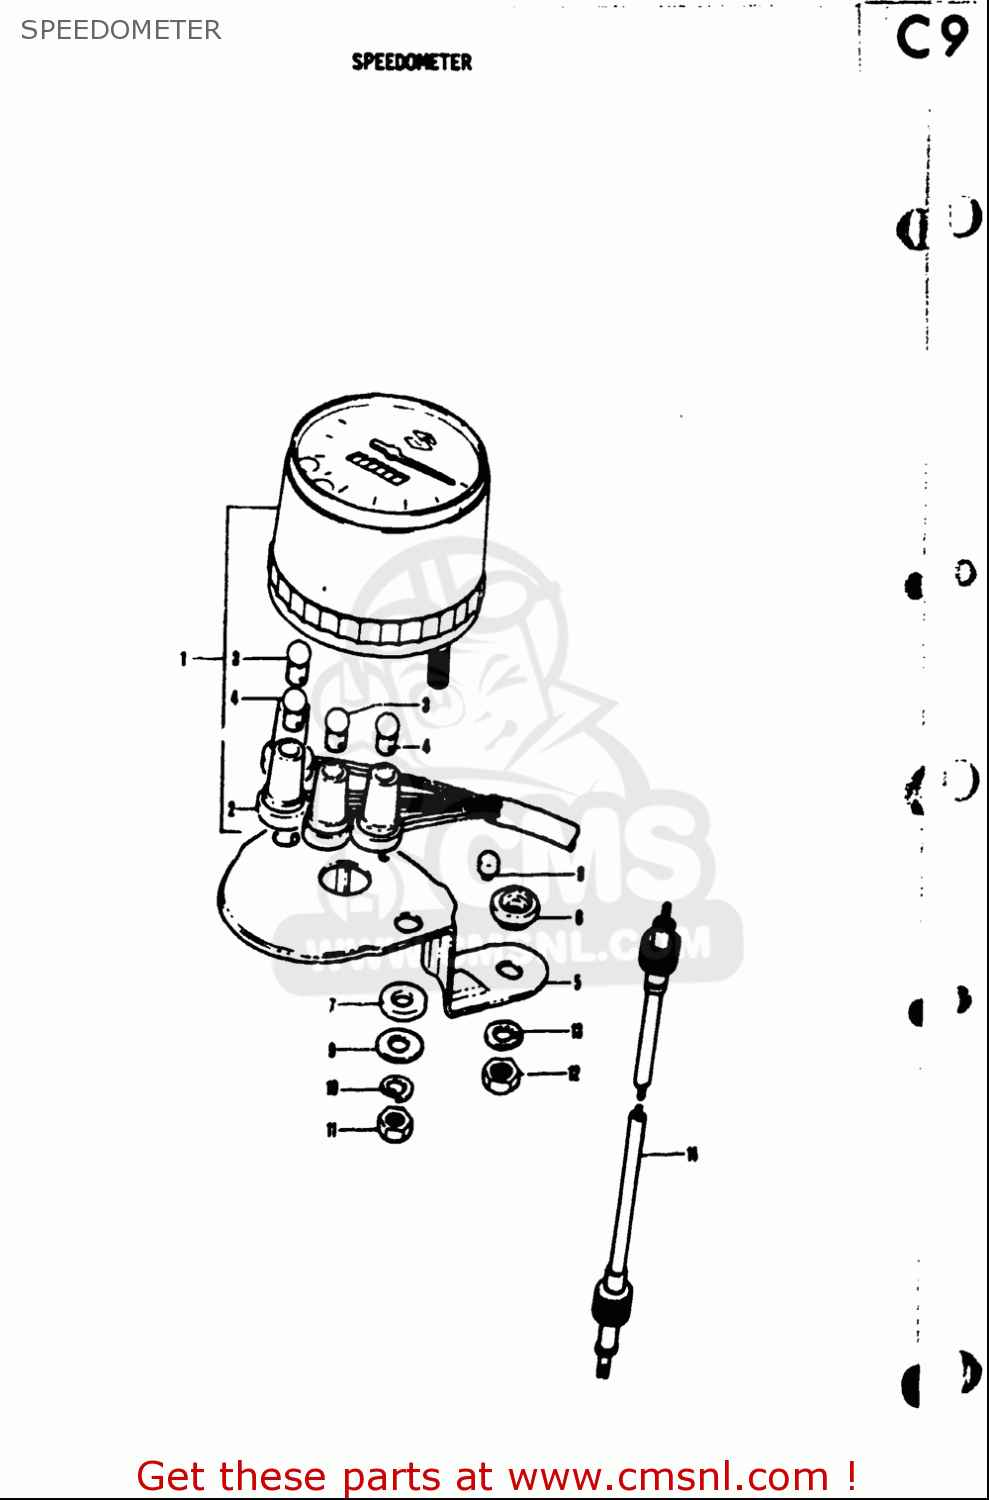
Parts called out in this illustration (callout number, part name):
3	BULB(6V/3W)
4	BULB(6V1.7W,STANLEY,A61A)
6	CUSHION,METER
7	CUSHION
9	WASHER(5.5X16X1.5)
10	WASHER,LOCK
11	NUT
12	NUT
13	WASHER,LOCK
14	CABLE ASSY,SPEEDOMETER
